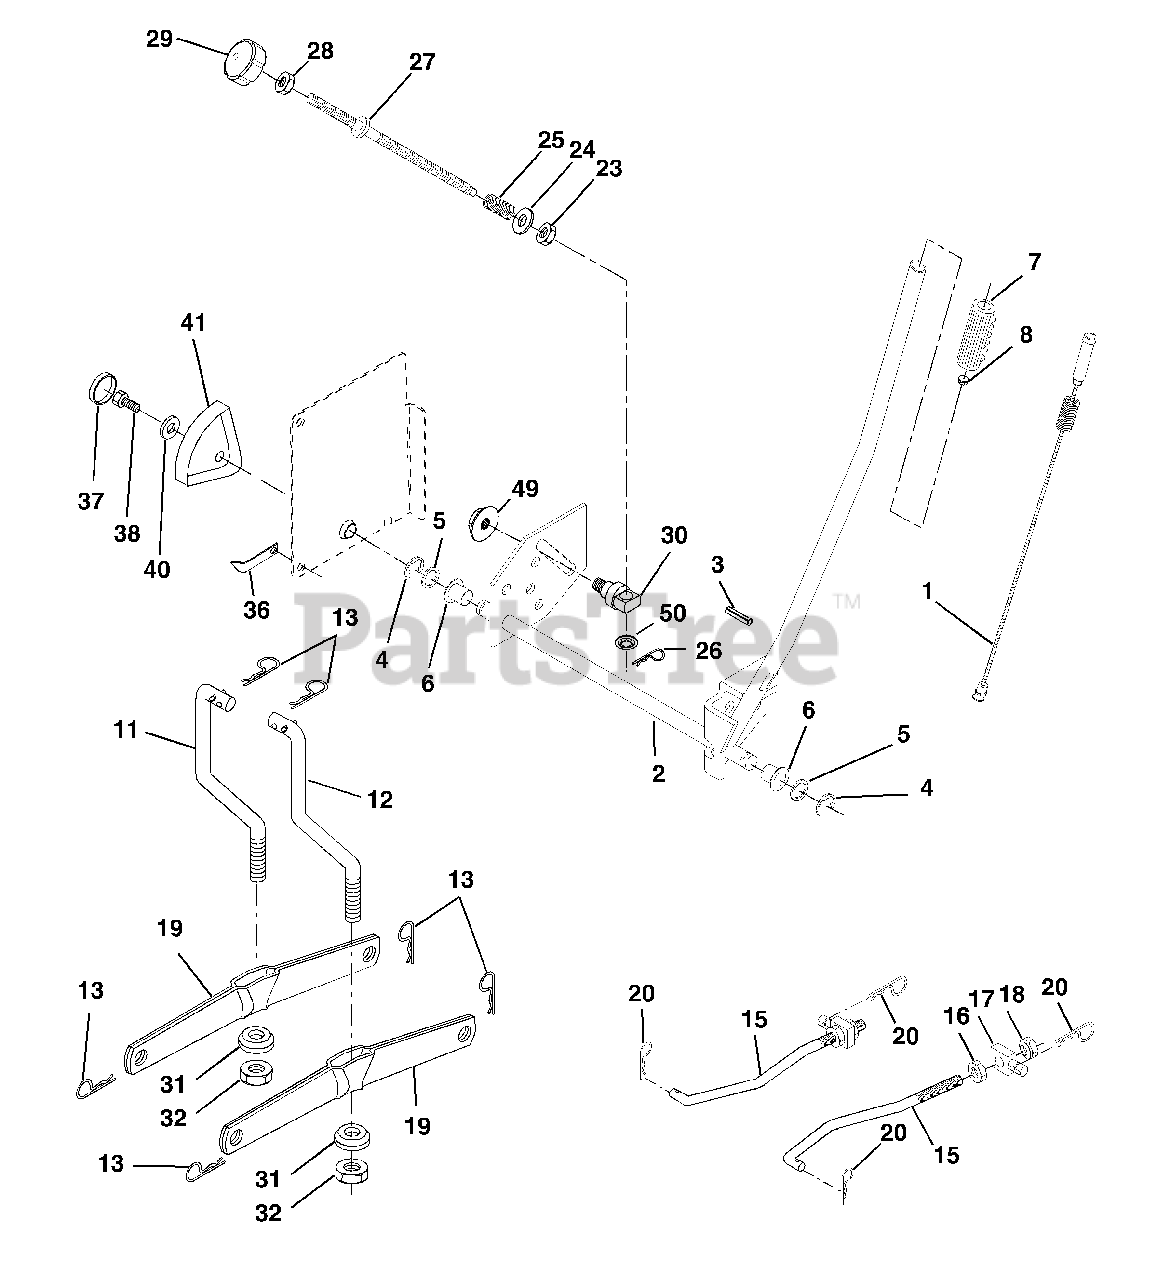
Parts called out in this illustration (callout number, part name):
1	Wire Asm Inner/Sprg W/plunger LT
2	Shaft Asm Lift RH w/Inf
3	Pin Groove 1 500 Zinc
4	E Ring #5133-62
5	Washer 21/32 X 1 X 21 Ga
6	Bearing Nylon Blk 629 Id
7	Grip Handle
8	Button Plunger Yellow
11	Link Lift LH Fixed Length
12	Link Lift RH Fixed Length
13	Retainer Spring
15	Link Front
16	Nut Jam Hex 1/2-13 Unc
17	Trunnion Blk Zinc
18	Nut Lock w/Wsh 1/2-13 Unc
19	Arm Suspension Rear
20	Retainer Spring
23	Nut Special
24	Washer 13/32 X 5/8 X 16 Ga
25	Spring 2-1/8"
26	Retainer Clip
27	Rod Adj Lift Zinc 7.49 Wrk Lg
28	Nut Hex Jam 3/8-16 Unc
29	Knob Inf 3/8-16 Unc Blk W/sym
30	Trunnion Infin Height
31	Bearing Pvt Lift
32	Nut Crownlock 3/8 - 24
36	Pointer Height Indicator
37	Plug Hole Blk 1.485/1.515 Dia.
38	Screw Thdrol 5/16-18 x 1
40	Washer 11/32 x 1-1/2 10 Ga.
41	Indicator Height STLT
49	Nut Hex Flange Lock
50	Nut PUsh Phos & Oil
